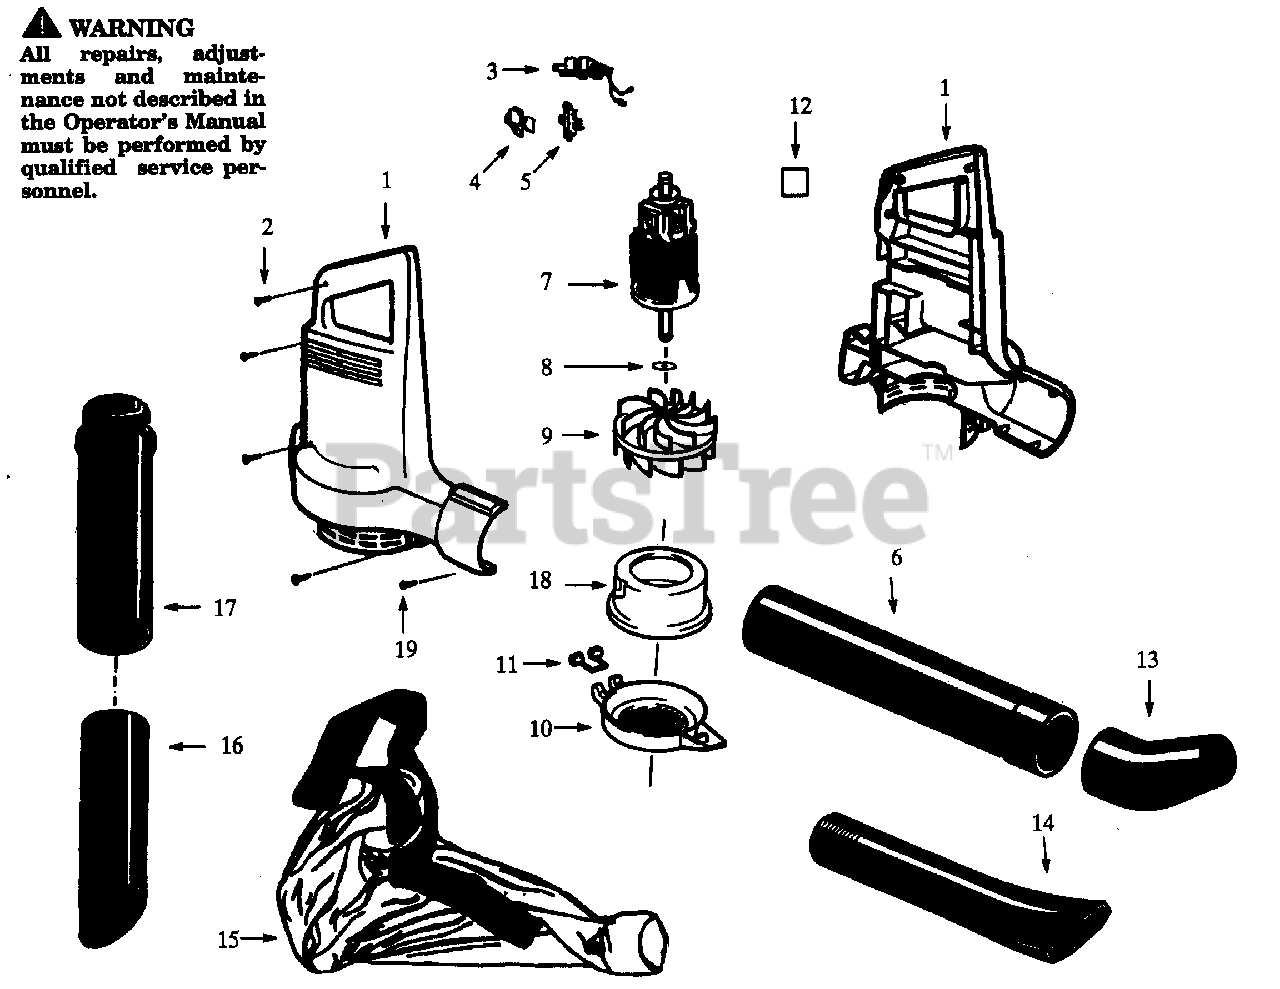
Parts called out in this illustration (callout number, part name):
1	Housing Set
3	Wire Harness (Incl. 5)
4	Switch Cover
6	Blower Tube
7	Motor Ass'y
9	Impeller
10	Inlet Cover
13	Concentrator Nozzle
14	Flare Nozzle
15	Vacuum Bag Kit
16	Vacuum Tube (Lower)
17	Vacuum Inlet Tube
18	Restrictor-Inlet
19	Screw-Housing
